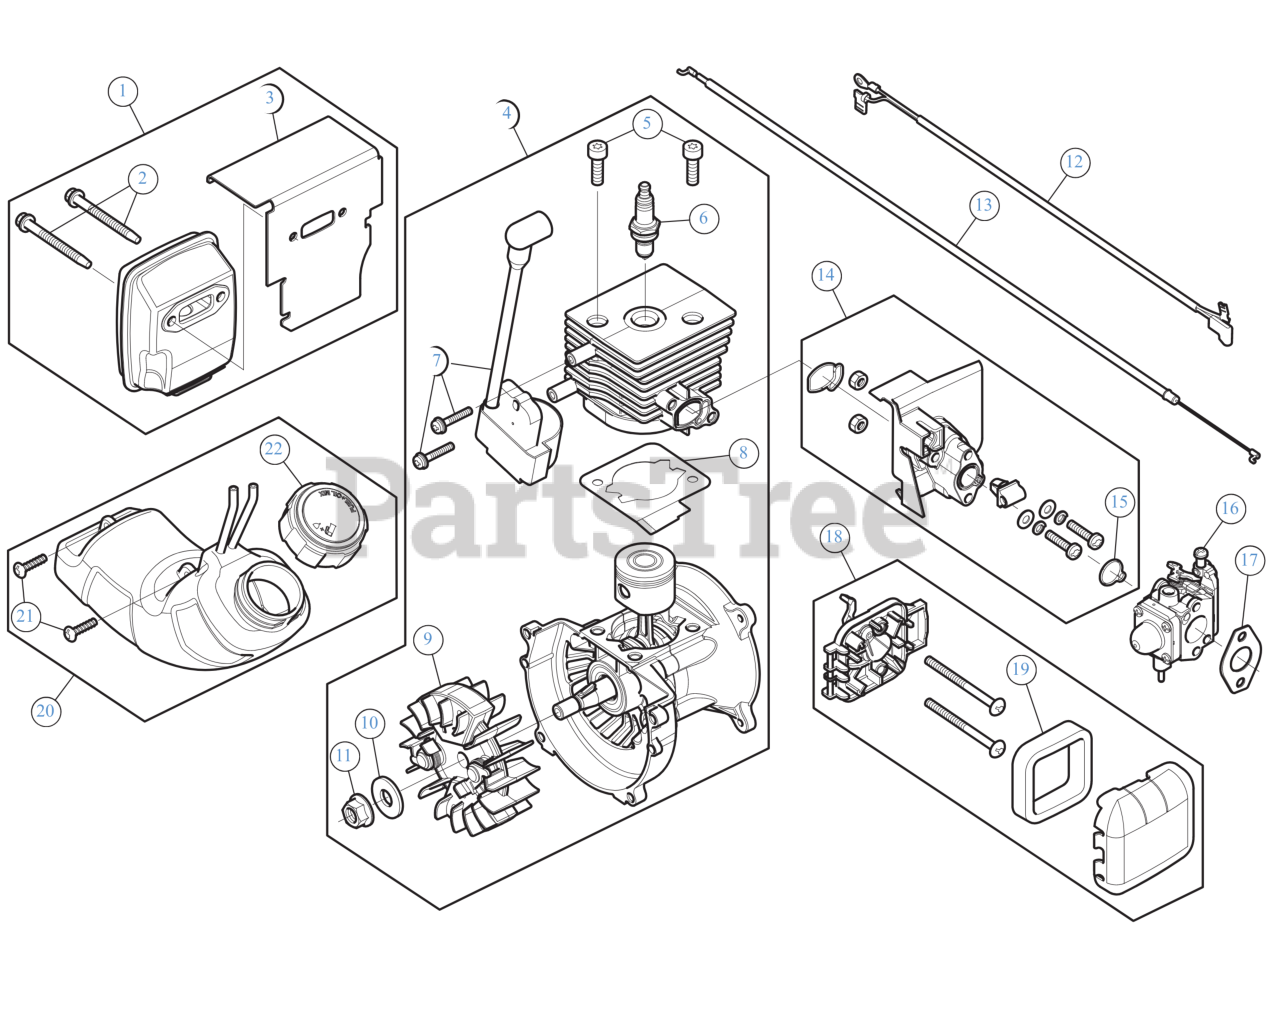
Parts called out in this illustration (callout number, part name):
1	MUFFLER ASSEMBLY 27CC
2	MUFFLER SCREW
3	MUFFLER GASKET
4	SHORT BLOCK
5	SCREW 1/4 x 20 x .8125
6	SPARK PLUG
7	MODULE
8	GASKET CYL
9	FLYWHEEL ASSEMBLY
10	WASHER .406X1.0X.095
11	NUT 3/8-24
12	LEAD WIRE
13	THROTTLE CABLE
14	INTAKE ASSEMBLY
15	O-RING
16	CARBURETOR ASSEMBLY
17	GASKET CARB
18	AIR CLEANER ASSEMBLY
19	AIR FILTER
20	FUEL TANK ASSEMBLY
21	SCREW 8-16 x 3/4
22	FUEL CAP
